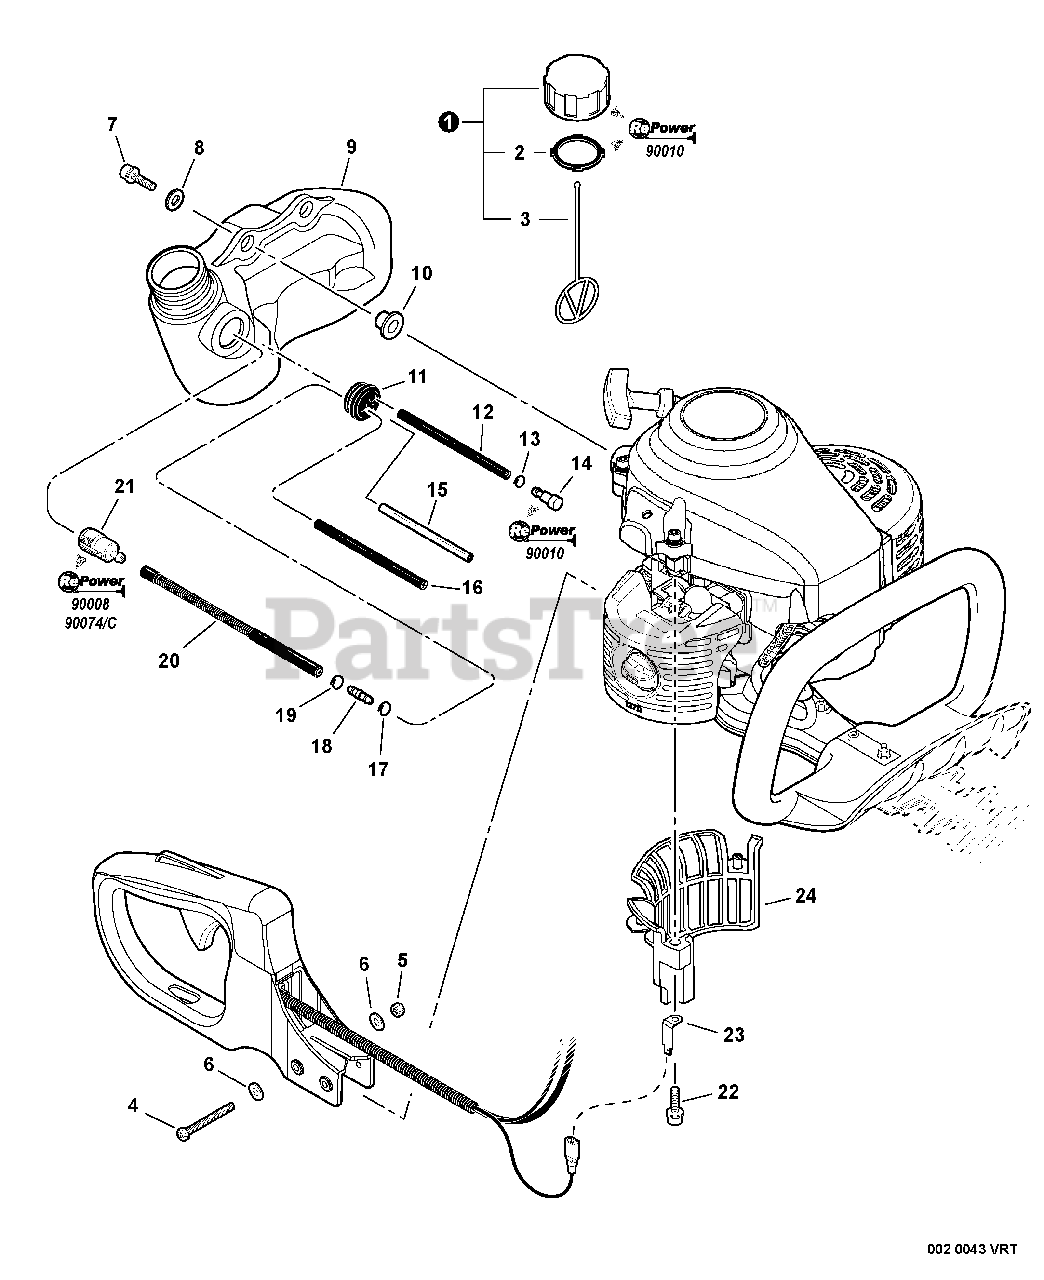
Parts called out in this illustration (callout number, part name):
1	CAP ASSY
2	GASKET, CAP
3	CONNECTOR, CAP
4	SCREW - 5X45
5	LOCKNUT - 5
6	WASHER - 5
7	SCREW - 5X20
8	WASHER - 5
9	TANK, FUEL
10	COLLAR - 5
11	GROMMET
12	PIPE - 3X6X65 -- BLACK
13	CLIP - 6.6
14	VENT, FUEL TANK
15	PIPE - 3X6X75 -- CLEAR
16	PIPE - 3X6X105 -- BLACK
17	CLIP - 6
18	CONNECTOR, PIPE
19	CLIP - 6.5
20	PIPE, FUEL - CORRUGATED
21	FILTER, FUEL
22	SCREW - 5X16
23	TERMINAL - GROUND
24	GUARD, DEBRIS
25	RePower FILTER KIT
26	Repower CAP AND VENT KIT
27	RePower TUNE-UP KIT
